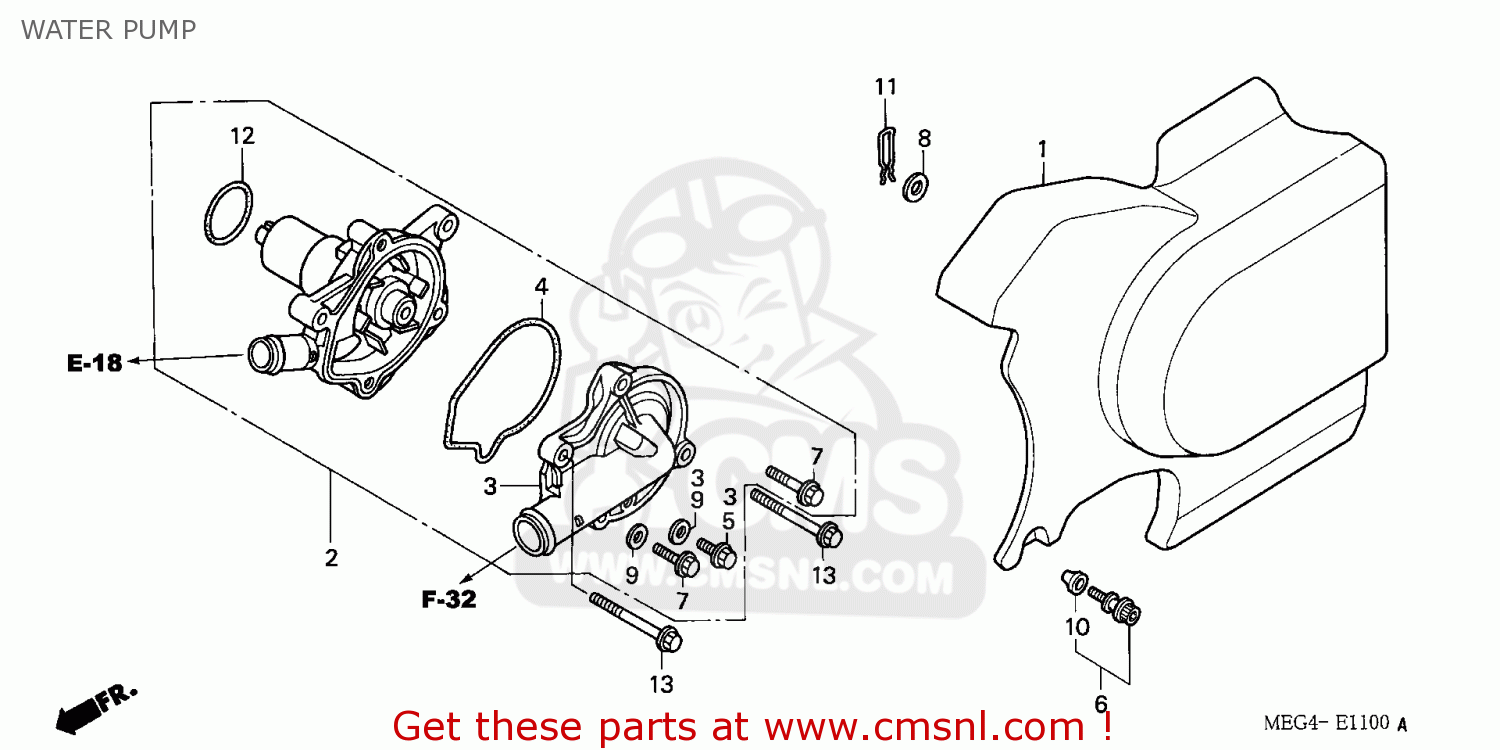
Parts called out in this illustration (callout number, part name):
1	COVER COMP,L REAR
2	PUMP ASSY,WATER
3	COVER ASSY,WATER
4	GASKET,W-PUMP COV
6	BOLT ASSY,SPECIAL
7	BOLT,FLANGE,6X25
8	WASHER, B SEALING
9	WASHER,SEALING,6.
10	RUBBER,MOUNT
11	PIN,LOCK 10MM
12	O-RING 32.95X2.62
13	BOLT,FLANGE,6X45
